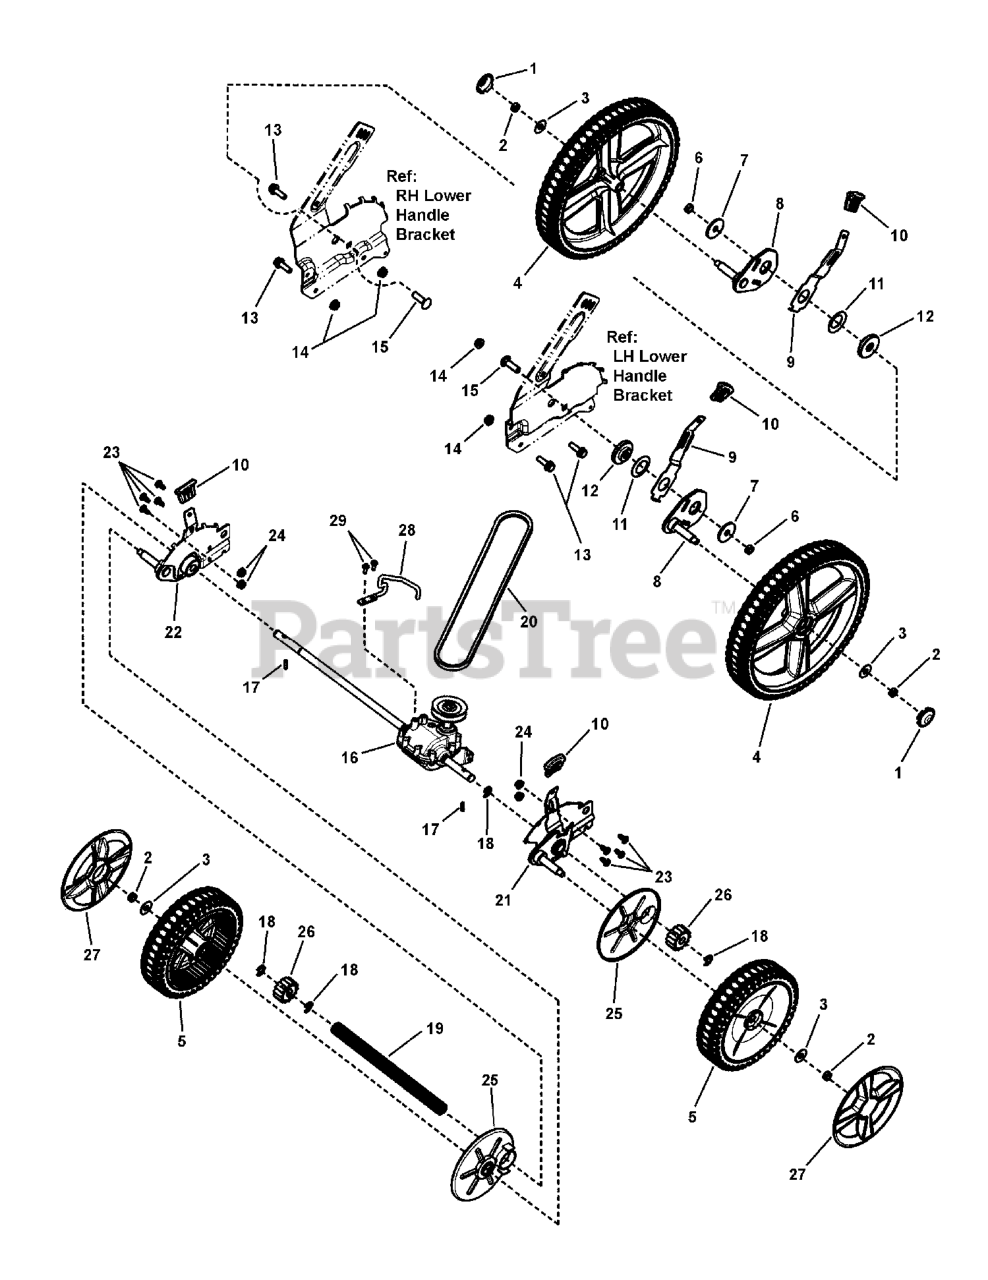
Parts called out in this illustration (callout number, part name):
1	HUBCAP, 12" Rim Yellow
2	NUT, Hex Center Lock, 3/8-16, GR 5
3	WASHER, 1" OD x .387 ID Flat
4	WHEEL,12" x 2" Idle, w/Db Tread, Brute Yellow
5	WHEEL, 8" x 2" Drive, w/DB Tread P-290 Satin Black
6	NUT, 3/8-16 Hex Center Lock, YZ
7	WASHER, 13/32 x 1-1/2" x .120 Flat, YZ
8	ASSEMBLY, Wheel Bracket, Rear, High-Wheel (staked)
9	LEVER, Front, Height-Of-Cut, 22"
10	GRIP, Height Latch, P-391-St, Yellow
11	WASHER, 1" ID x 1.64 OD Bellville
12	BUSHING, Pivot, Hi-Wheel, Rear
13	BOLT, 5/16-18 x 1" Hex Flange Lock, GR 5, YZ
14	NUT, 5/16-18 Hex Flange Lock, GR 5, YZ
15	BOLT, 3/8-16 x 1-1/4" Round Head Square Neck Carriage, GR 5 YZ
16	TRANSMISSION, Variable Speed, Front Wheel Drive
17	PIN, Drive, 22" WBM, Front Wheel Drive
18	RETAINING RING
19	SHIELD, Axle
20	BELT, 3L, Traction Drive, 22" Walk Behind Mower, FWD
21	ASSEMBLY, Height-Of-Cut, LF, 22" WBM, Propelled
22	ASSEMBLY, Height-Of-Cut, RF, 22" WBM, Propelled
23	SCREW, 1/4-20 x .550 Pan Head Torx (T-30)
24	NUT, 1/4-20 Hex Flange Lock, YZ
25	SHIELD, Dust, 22" WBM, Front Wheel Drive
26	GEAR, Pinion, 22" WBM, Front Wheel Drive
27	HUBCAP, 8"& 9" Wheel Spoked, P-391 St Yellow
28	BELT GUIDE, Front Wheel Drive
29	SCREW, #10-14 x 1/2" Hex Washer Self-Tap, Plastite
